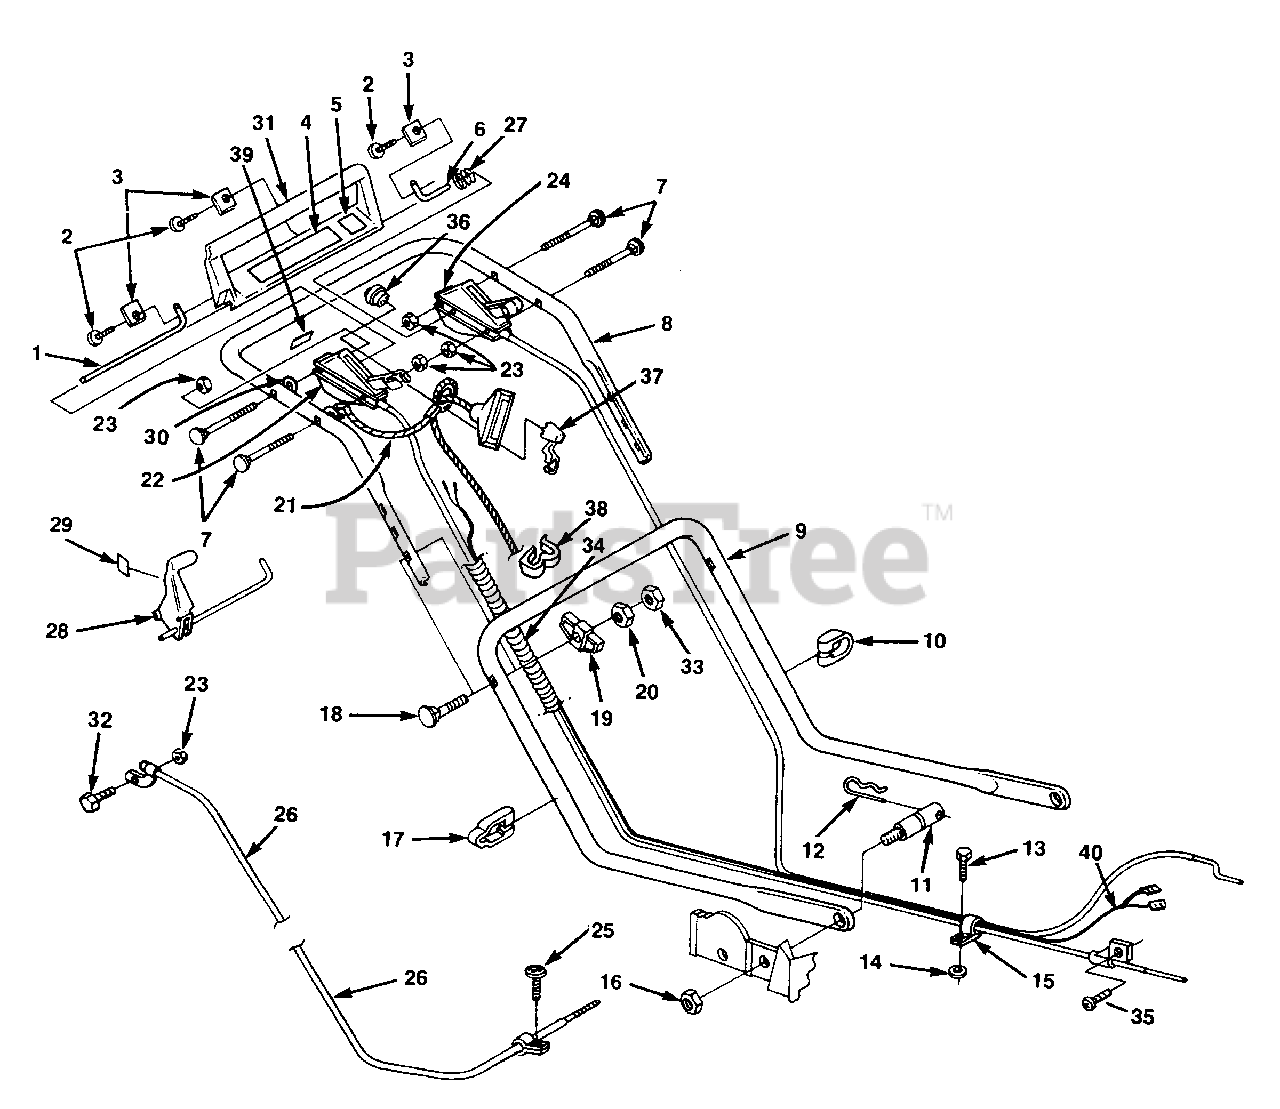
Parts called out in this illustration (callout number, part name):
1	SHAFT- Pivot
3	CLAMP- Pivot shaft
4	DECAL- Brake bail
5	DECAL- Blade - rotate
6	SHAFT- Pivot
7	BOLT- Sq. neck
8	HANDLE- Upper
9	HANDLE- Lower
10	CLAMP- Cable single
12	PIN- Cotter hair
16	NUT- Flange
17	CLAMP- Cable double
19	KNOB- Handle
20	NUT
21	ROPE- Restraint
22	CONTROL- Manual start
24	CONTROL- Throttle
26	CABLE- Traction
27	SPRING
28	LEVER- Assy. - Traction
30	WASHER
31	BAIL- Brake control
34	COVER- Control cable
35	SCREW- 10-32 x 3/8
36	SWITCH
37	HOUSING- Switch
38	CLIP- Cover
39	DECAL
40	HARNESS- Wiring
